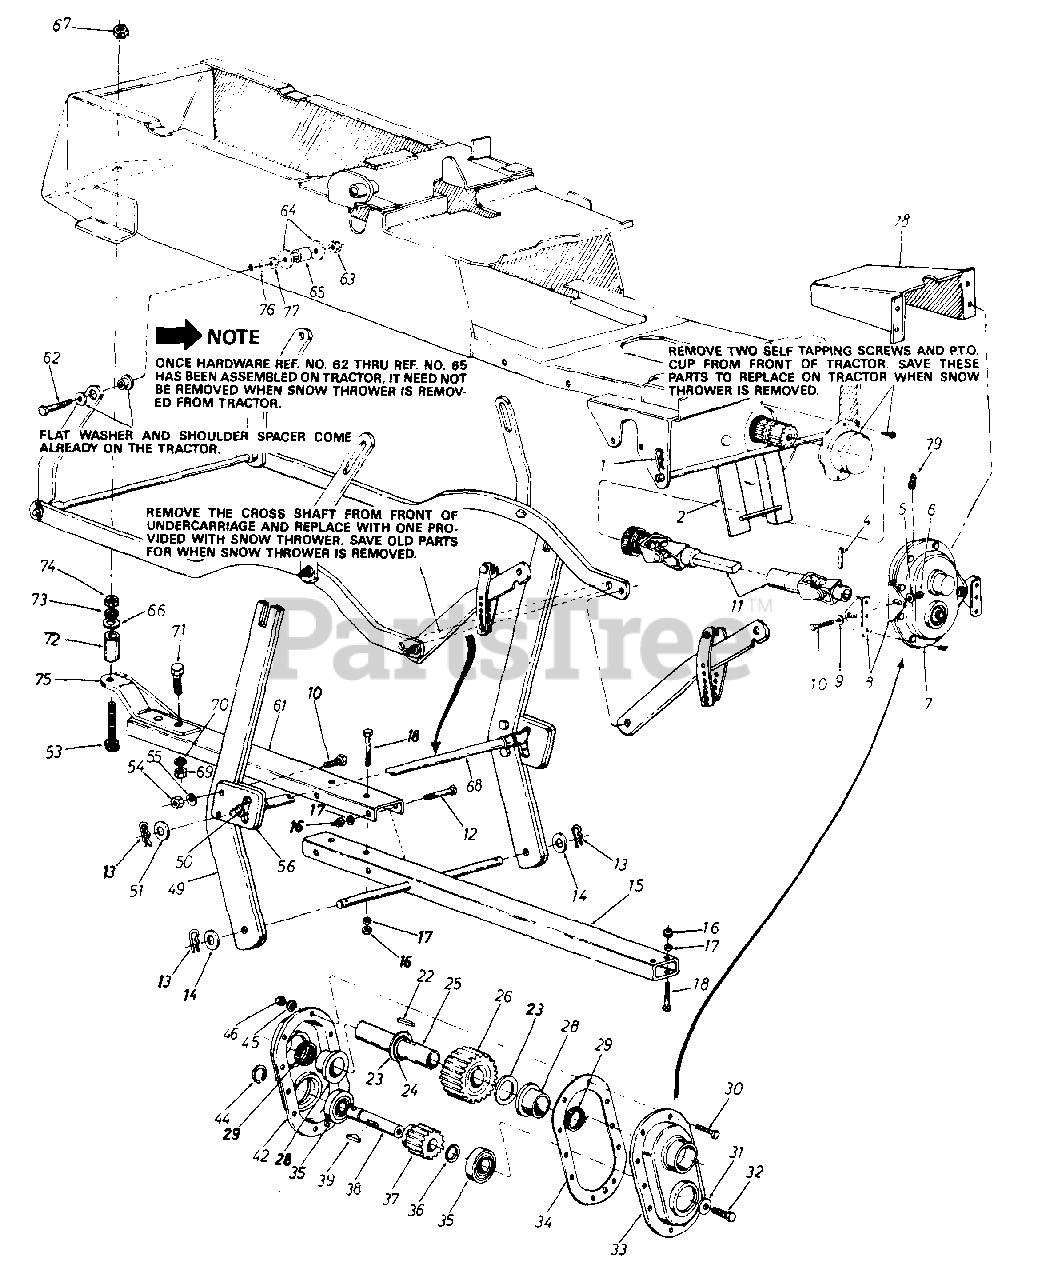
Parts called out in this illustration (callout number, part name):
1	Intern. Cotter Pin 3/4" Dia.
2	Guide Bracket Ass'y.
4	Roll Pin Spirol 5/16" Dia. x 2.5" Lg.
5	Belleville Wash. .341" I.D. x .88" O.D.
6	Hex Nut 5/16-18 Thd.
7	Gear Box Ass'y. Comp.
8	Gear Box Support Brkt.
9	Belleville Wash. .341" I.D. x .88" O.D.
10	Hex Bolt 5/16-18 x 1.25" Lg. (Grade 5)
11	Universal Drive Shaft Ass'y.
12	Hex Bolt 3/8-24 x 4.50"
13	Hair Pin Cotter
14	Fl.-Wash. .75" I.D. x 1.5" O.D.
15	Lift Shaft Ass'y.
16	Hex Ins. Jam L.-Nut 3/8-24 Thd.
17	L.-Wash. 3/8" I.D.
18	Hex Bolt 3/8-24 x 2.75" Lg.
22	Hi-Pro Key 1/4" x 7/8" Dia.
23	Fl.-Wash. 1.31" I.D. x 2.00" O.D. x .060
24	Snap Ring for 1.25" Dia. Shaft
25	Gear Shaft 1.25" Dia. x 6.0" Lg.
26	28 Teeth Spur Gear
28	Flange Bearing 1.25" I.D. x 1.75" O.D.
29	Oil Seal 1.25" I.D. x 1.75" O.D. x .26
30	Hex Bolt 1/4-28 x .88" Lg.
31	Fl.-Wash. .40" I.D. x 1.25" O.D. x .160
32	Hex L.-Bolt 3/8-24 x 1.00" Lg.
33	Gear Housing Half - L.H.
35	Ball Bearing 1.00" I.D. x 2.00" O.D.
36	Fl.-Wash. 1.03" I.D. x 1.63" x .090
37	15 Teeth Spur Gear
39	Woodruff Key 1/4" x 3/4" Dia.
42	Gear Housing Half - R.H.
44	Snap Ring for 1.00" Dia. Shaft
45	Spring Wash. 1/4" I.D.
46	Hex Nut 1/4-28 Thd.
51	Fl.-Wash. .62" I.D. x 1.12" O.D.
53	Hex Bolt 5/8-11 x 4.00" Lg.
54	Hex Nut 5/16-18 Thd.
55	L.-Wash. 5/16" I.D.
62	Hex Bolt 3/8-24 x 2.50" Lg. (Grade 5)
63	Hex Jam L.-Nut 3/8-24 Thd.
64	Fl.-Wash. .375" I.D. x 1.00" O.D. x .135"
65	Spacer .375" I.D. x .625" O.D. x .445
66	Fl.-Wash. .62" I.D. x 1.12" O.D.
67	Hex Jam L.-Nut 5/8-11 Thd.
68	Cross Shaft Ass'y.
69	Hex Nut 1/2 13 Thd.
70	L.-Wash. 1/2" I.D.
71	Hex Bolt 1/2-13 x 1.25" Lg.
72	Spacer .65" I.D. x 2.12" Lg.
73	L.-Wash. 5/8" I.D.
74	Hex Jam Nut 5/8-11 Thd.
77	Hex Nut 3/8-24 Thd.
78	Drive Shaft Cover
79	Grease Fitting
